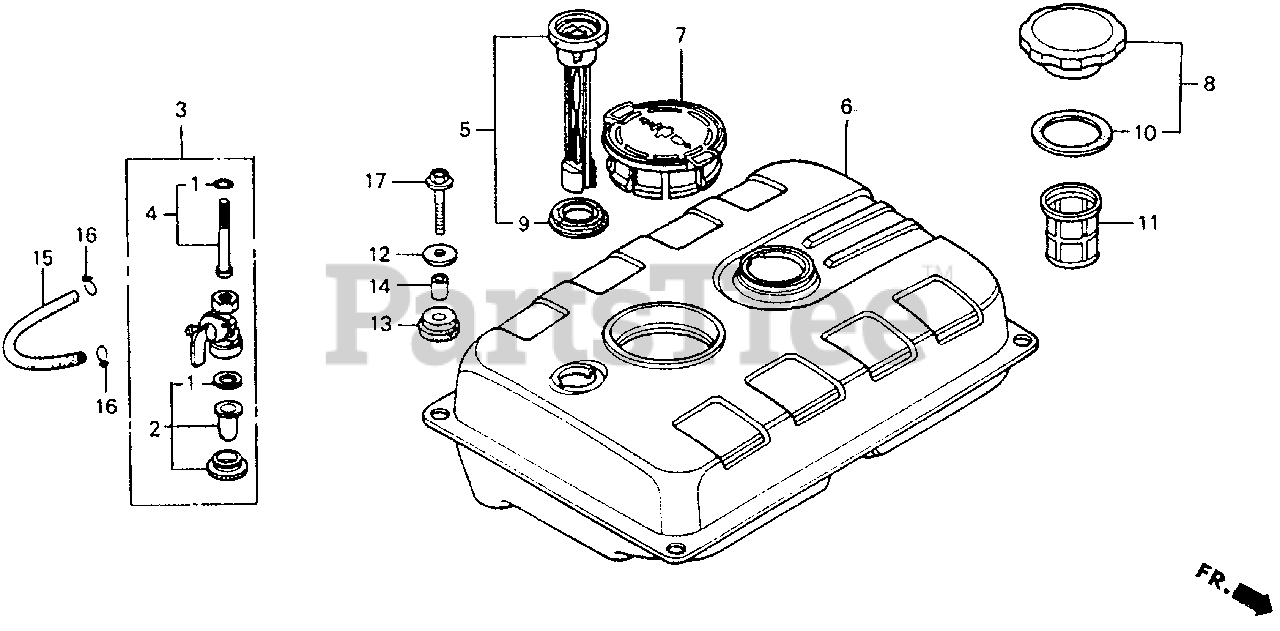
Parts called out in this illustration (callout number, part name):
1	GASKET SET, PETCOCK (CONTAINS 1 LARGE & 1 SMALL. USE AS NEEDED)
2	CUP, FUEL STRAINER
3	PETCOCK ASSY.
4	SCREEN SET
5	METER, FUEL
6	TANK, FUEL *NH31* (MCKINLEY WHITE) (NOT AVAILABLE)
7	CAP, SPARK PLUG HOLE
8	CAP, FUEL TANK
9	GASKET C, FUEL METER
10	GASKET, FUEL FILLER CAP
11	FILTER, FUEL
12	WASHER, TANK RUBBER
13	CUSHION, TANK RUBBER
14	COLLAR, TANK RUBBER
15	BULK HOSE, FUEL (4.5X3000) (4.5X105)
16	CLIP, TUBE (B8)
17	BOLT, FLANGE (6X25)
